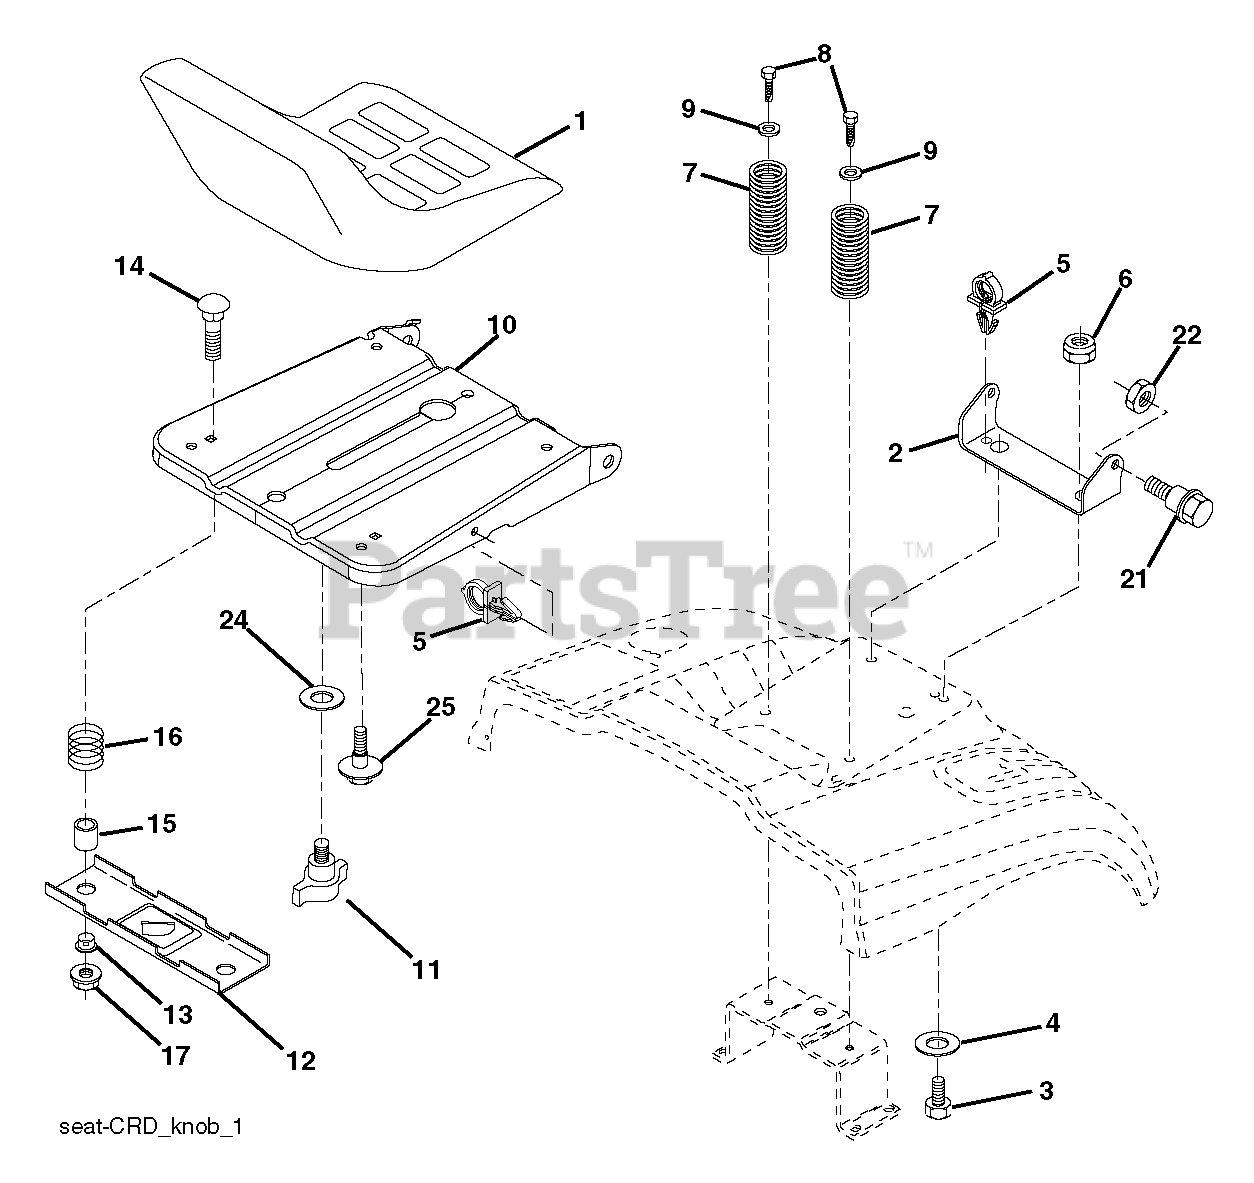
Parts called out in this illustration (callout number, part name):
1	SEAT.XG110.BLK.NO/LOGO
2	SEAT PIVOT BRKT
3	BOLT, HEX 3/8-16X1
4	WASHER PM
5	PUSH CLIP
6	NUT
7	SPRING COMPRESSION
8	SCREW 3/8-16X1
10	PAN.ASM.SEAT.1SLOT
11	KNOB.SEAT.ADJ.WINGNUT
12	BRKT.MNTNG.SWITCH.SEAT.BLACK
14	BOLT.ROUND.HEAD.SQUARE.NECK
15	SPACER SPLIT 28X.96
17	NUT T
21	BOLT.SHOULDER.5/16-18
22	NUT.71038.31-18.HEX.NYLOCK
25	BOLT,SHOULD
